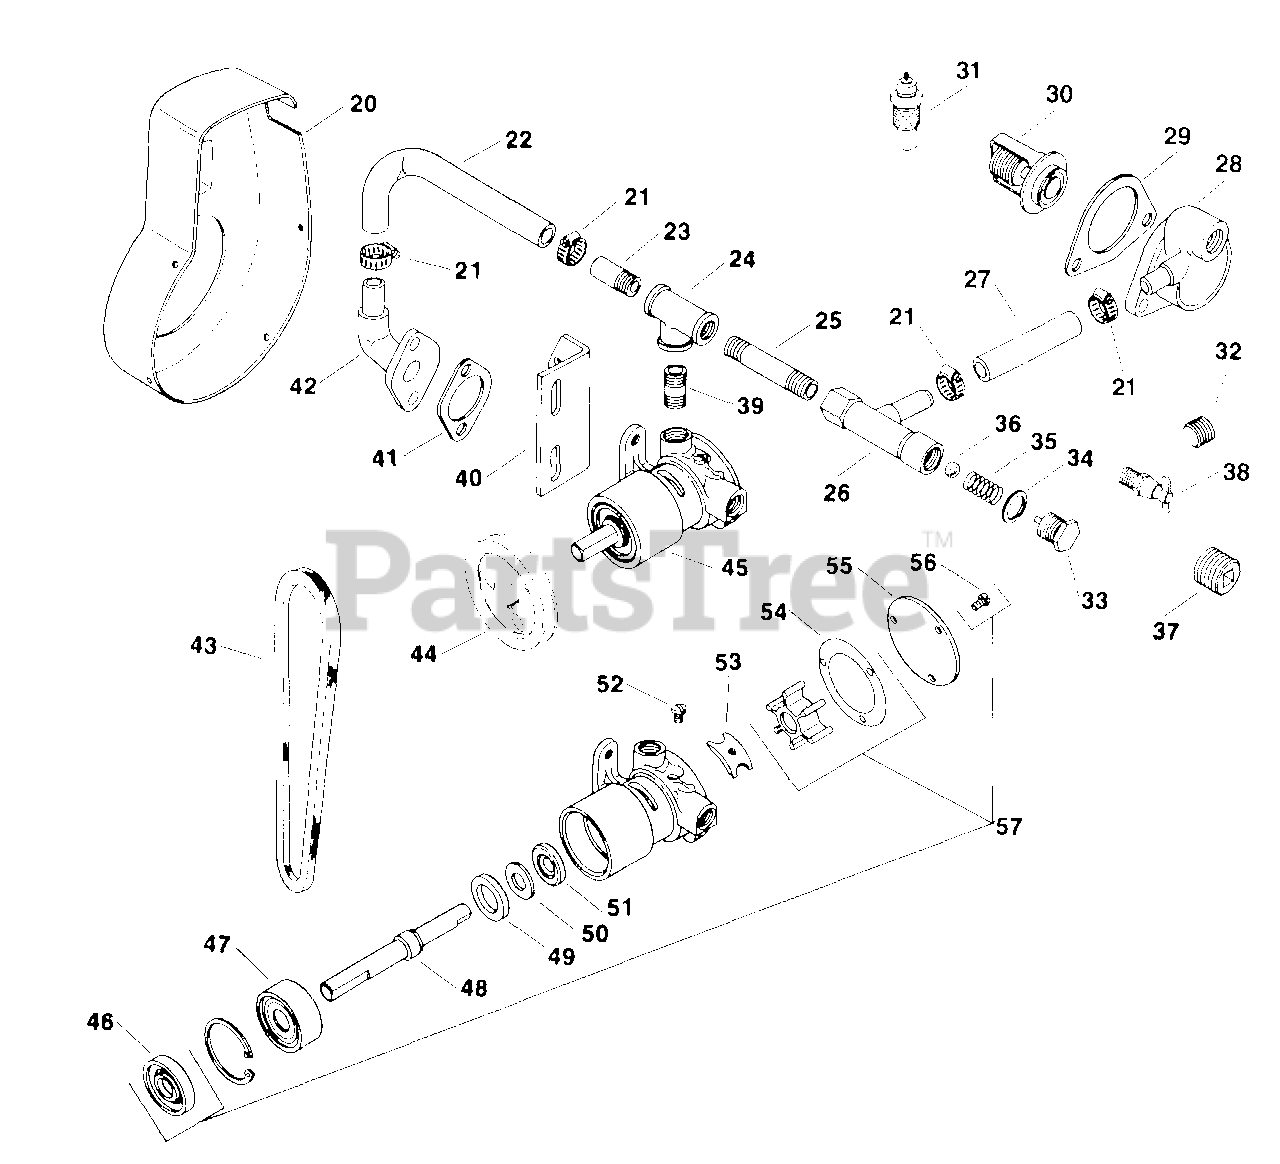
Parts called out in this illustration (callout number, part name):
21	CLAMP, HOSE USE 25 237 12-S
29	GASKET - DISCONTINUED
30	THERMOSTAT - USE 41 453 01
30	THERMOSTAT - DISCONTINUED
31	Switch, water temperature
32	PLUG,PIPE 1/2 NPTF SQUARE HD USE 25 139 54-S
38	Valve
41	GASKET - DISCONTINUED
46	SEAL - DISCONTINUED
47	BEARING - DISCONTINUED
48	SHAFT - DISCONTINUED
49	SEAL - DISCONTINUED
53	CAM - DISCONTINUED
56	SCREW - DISCONTINUED
57	KIT, WATR PMP RPR - DISCONTINUED
